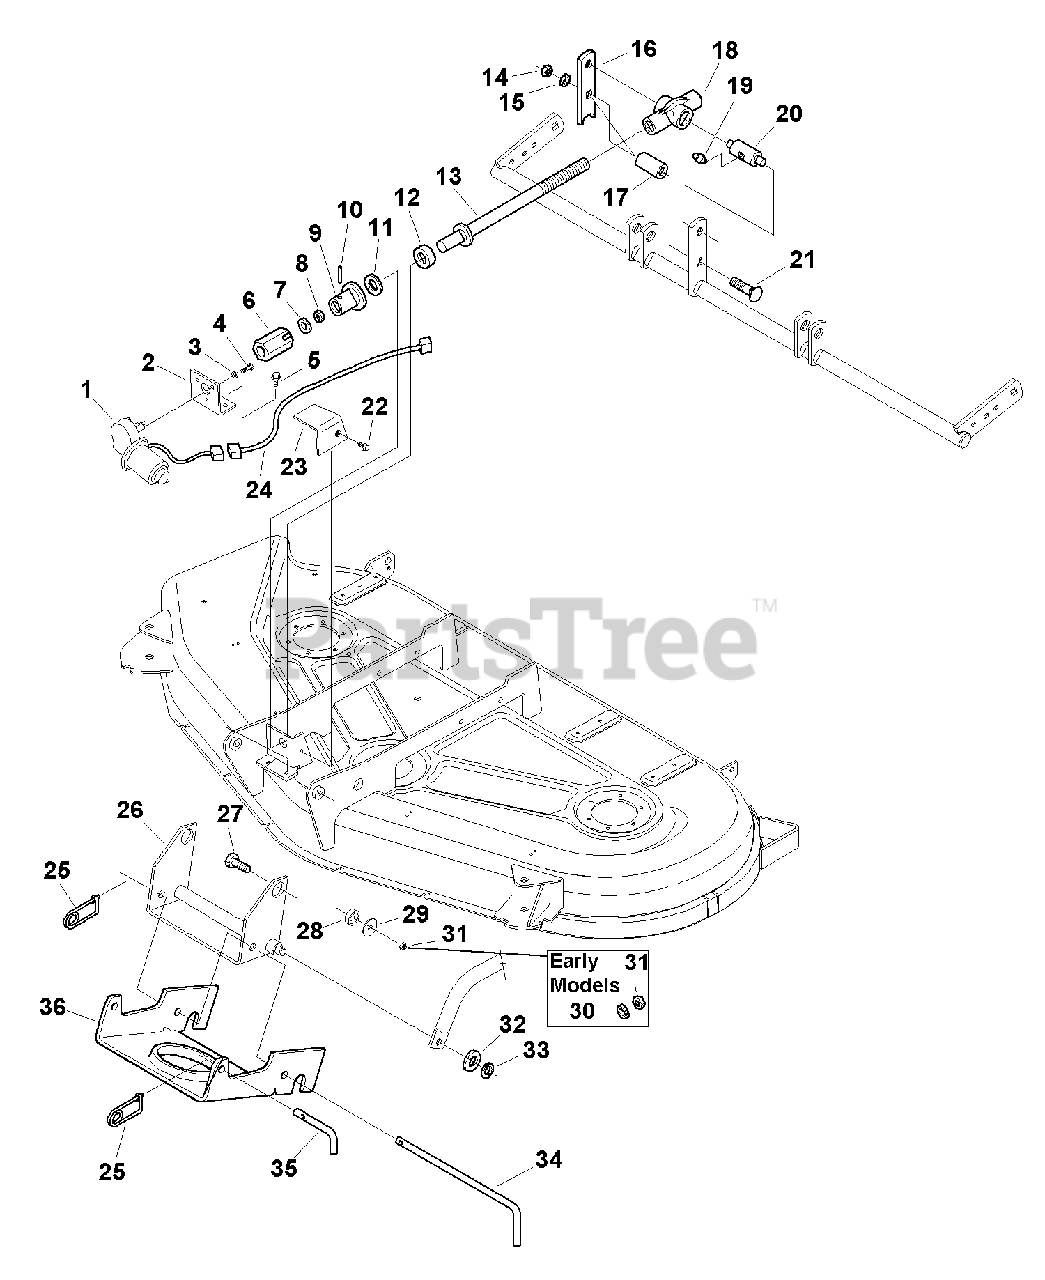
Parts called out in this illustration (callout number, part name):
1	MOTOR, Electric Cutting Height Adjust
2	BRACKET
3	LOCKWASHER, 1/4
4	CAPSCREW, Hex Head, 1/4-20 x 3/4
5	CAPSCREW, Hex Head, Taptite, 5/16-18 x 3/4
6	ADAPTER, Motor
7	WASHER, Plain, 1/4
8	NUT, Hex, Center Lock, 1/4-20
10	PIN, Roll, 3/16 x 1-1/2
11	WASHER, Nylon
12	BEARING, Thrust
13	ASSEMBLY, Shaft
14	NUT, 1/2-13
15	LOCKWASHER, 1/2
19	FITTING, Lube
21	CARRIAGE BOLT, 1/2-13 x 2-1/2
22	CAPSCREW, Hex Head, Taptite, 5/16-18 x 1/2
23	COVER, Motor
24	HARNESS, Mower Lift
25	PIN, Safety
26	ASSEMBLY, Hitch & Shaft
27	CAPSCREW, Hex Head, 3/8-16 x 1-1/2
29	WASHER
30	LOCKWASHER, 3/8 (Early Models)
31	NUT, 3/8-16 (Early Models)
31	NUT, Hex Alm Insert Lock, 3/8-16 (Later Models)
32	WASHER, 5/8
33	RING, Retaining, 5/8
36	ASSEMBLY, Hitch
